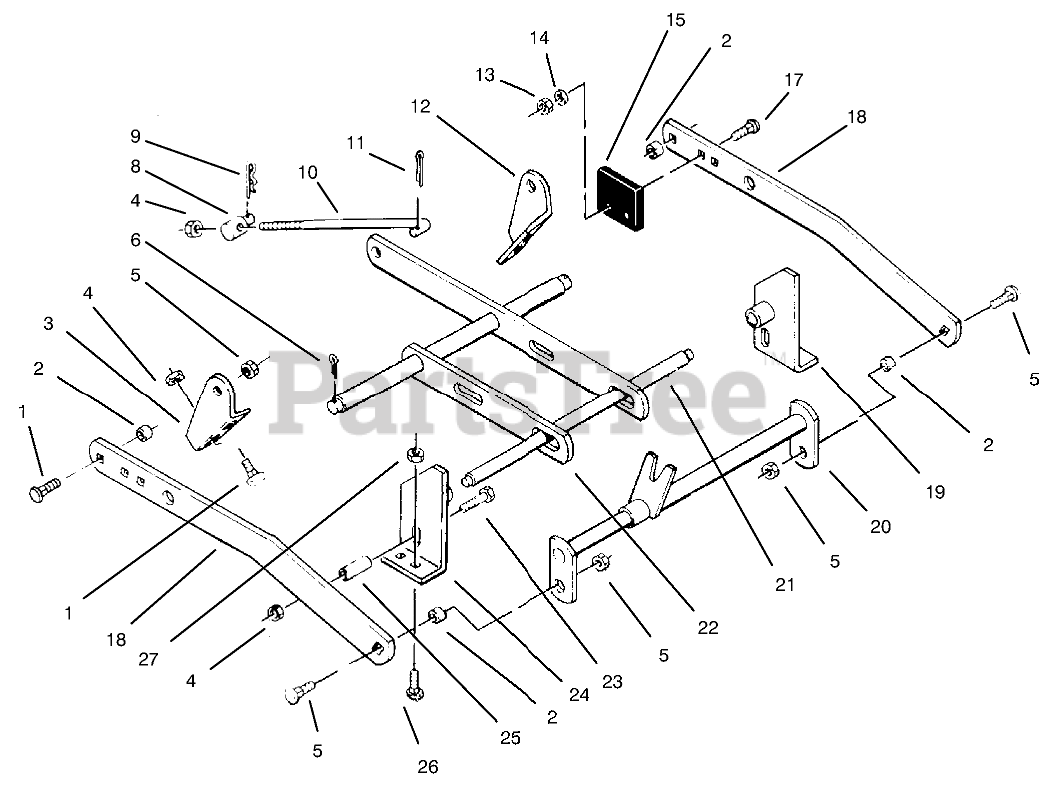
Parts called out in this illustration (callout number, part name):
1	BOLT-CARR
2	SPACER
3	Bracket-Rt. Rear
4	NUT-LOCK, NI
5	LOCKNUT-FLANGE
6	PIN-COTTER
8	TRUNNION-LIFT
9	PIN-HAIR
10	LIFT ROD
11	PIN-COTTER
12	Bracket-L.H. Rear
13	NUT-LOCK, NI
14	WASHER-FLAT
15	BUMPER
17	SCREW-CARR
18	Bar Draft
19	Bracket-L.H.
20	Hitch
21	Front Shaft
22	Leveler
23	BOLT-CARR
24	Bracket-R.H.
25	SPACER
26	BOLT-CARR
27	NUT-LOCK, NI
